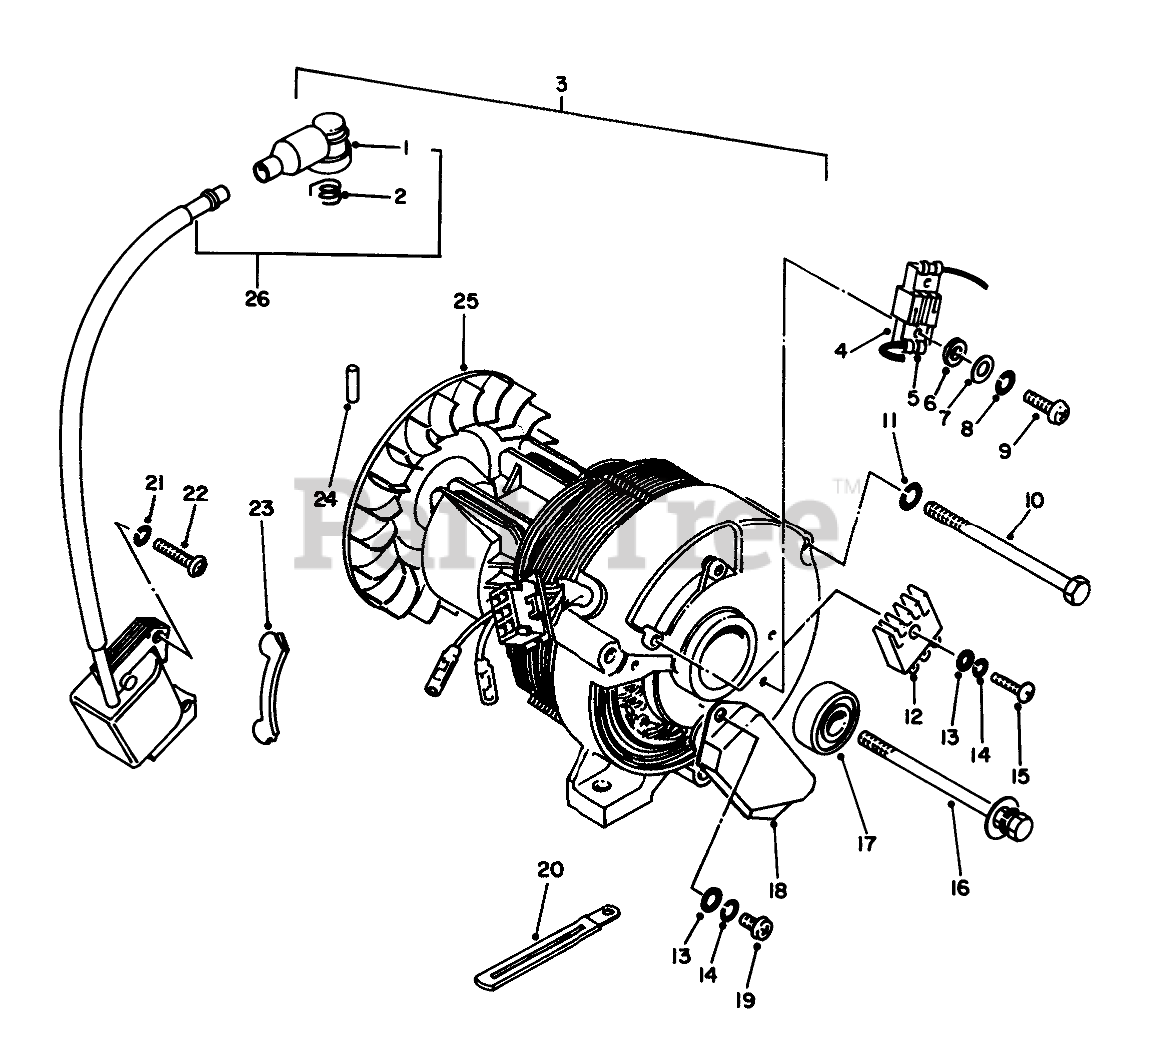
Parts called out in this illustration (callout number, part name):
1	CAP ASM
2	Spring
3	Generator Assembly
4	Holder-Brush
5	BRUSH
6	Bushing
7	Washer
8	Lockwasher
9	Screw
11	LOCKWASHER
12	Diode
13	WASHER
14	Washer
15	Screw
16	Bolt (L:125)
17	Bearing
18	A.V.R.
19	Screw
20	Clamp
21	Washer
22	Screw
23	Seal-Stator
25	Rotor
26	STARTOR ASM
